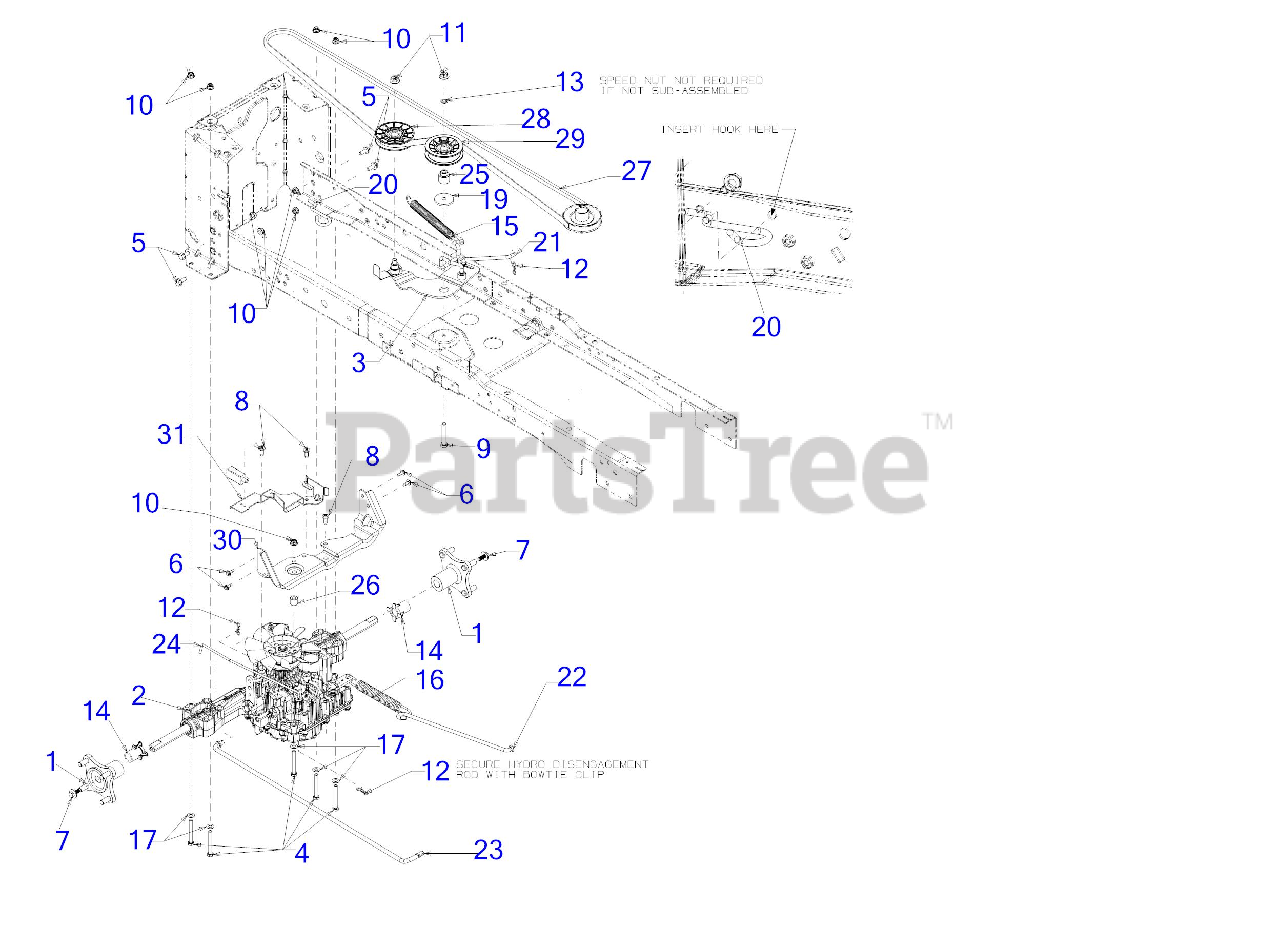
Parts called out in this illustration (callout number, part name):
1	HUB ASSEMBLY-WHEEL DD
2	TRANSMISSION ASSEMBLY
3	IDLER BRACKET ASSEMBLY
4	SCREW 5/16-18 x 2.5 GR 5
5	SCREW 5/16-18
6	SCREW M6-1 x .625
7	SCREW 5/16-24 x .85 GR5
8	SCREW 5/16-18 x .750
9	SCREW 3/8-16 x 2.25 GR5
10	FLANGE LOCK NUT 5/16-18
11	FLANGE LOCK NUT
12	BOW TIE COTTER PIN 1/4-5/16
14	AXLE SLEEVE .765 ID x 1.575 LG
15	EXTENSION SPRING .790 DIA x 8.41
16	EXTENSION SPRING 0.90 DIA x 8.14
17	FLAT WASHER
19	SHOULDER SPACER
20	DECK SPRING HOOK
21	IDLER BRACKET ROD
22	BRAKE ROD
23	HYDRO CONTROL ROD
24	HYDRO DISENGAGEMENT ROD
25	SHOULDER SPACER
26	SPACER .34 x .75 x .63 LG
27	V-BELT A SEC x 91.10
28	V-IDLER PULLEY 3.56 OD
29	FLAT IDLER PULLEY 3.00 OD
30	TRANSMISSON MOUNTING BRACKET
